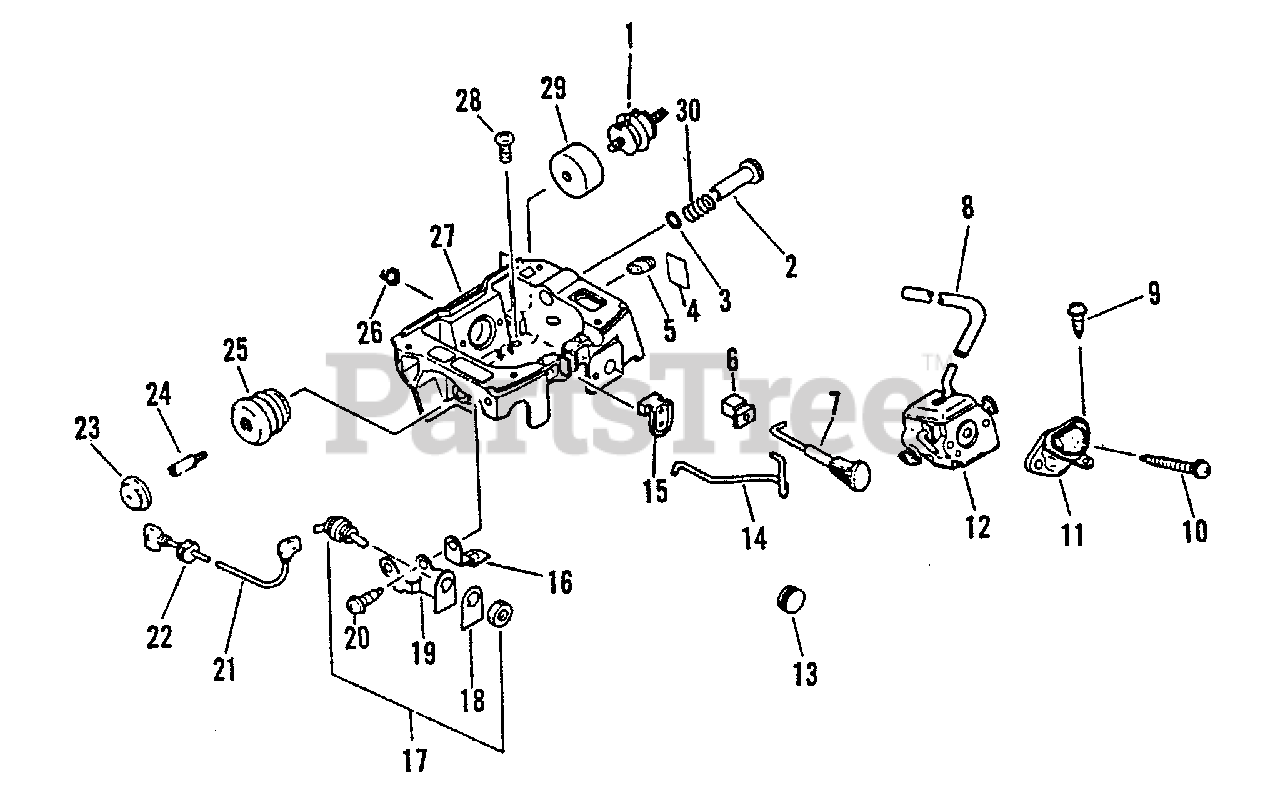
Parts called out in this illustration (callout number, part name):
1	CUSHION
2	SCREW, IDLE ADJUST
3	O-RING - 6
4	LABEL - IDLE
6	GROMMET
7	ROD, CHOKE
8	PIPE - IMPULSE
9	SCREW - 5X14
10	SCREW - 5X55
11	GASKET
12	CARBURETOR
14	ROD, THROTTLE
15	GUIDE, THROTTLE ROD
16	TERMINAL - GROUND
17	IGNITION SWITCH ASSY
18	LABEL - SWITCH
19	BRACKET, SWITCH
20	SCREW - 5X10
21	LEAD - GROUND
23	CAP, CUSHION
25	CUSHION
27	CASE, CARBURETOR
28	SCREW - 5X20
29	PLATE, CUSHION
30	SPRING, IDLE ADJUST
